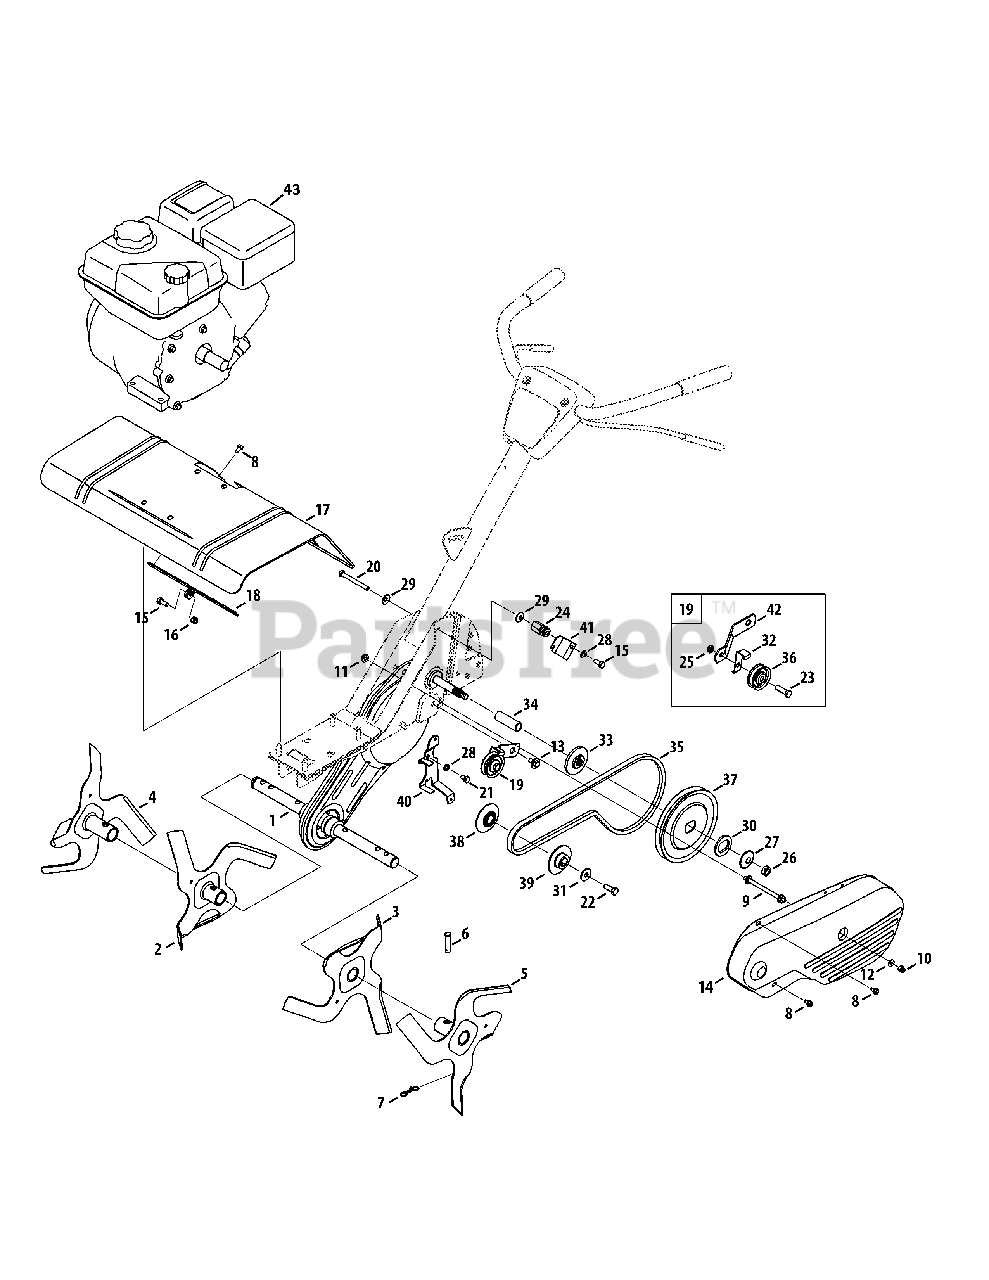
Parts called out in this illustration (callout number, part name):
1	Chain Case Assembly
2	Inner Tine Assembly, RH
3	Inner Tine Assembly, LH
4	Outer Tine Assembly, RH
5	Outer Tine Assembly, LH
6	Clevis Pin, .375 x 1.75
7	Bow Tie Cotter Pin
8	Screw, 1/4-20 x 0.500
9	Bolt, Belt Cover
10	Nut, 1/4-28, Lock
11	Nut, 5/16-18, Flange Lock
12	Flat Washer, .271 x .630 x .065
13	Shoulder Screw, .560 x .165 5/16-18
14	Belt Cover
15	Hex Head Screw, 5/16-18 x .75
16	Nut, 5/16-18, Flange Lock
17	Tine Shield
18	Bracket, Tine Shield
19	Idler Bracket Assembly
20	Hex Head Screw, 5/16-18 x 3.00
21	Hex Head Screw, 5/16-24 x .625
22	Hex Head Screw, 3/8-24 x 1.00
23	Hex Head Screw, 3/8-16 x 1.25
24	Hex Nut, 5/16-18
25	Jamlock Nut, 3/8-16
26	Nut, 1/2-20, Jam
27	Washer, .531 x 1.62 x .045
28	Lock Washer, 5/16
29	Bell Washer, .340 x .872 x .060
30	Flat Washer, 1.26 x 1.87 x .150
31	Bell Washer, .396 x 1.140 x .095
32	Belt Keeper
33	Pulley Adaptor
34	Spacer, .64 ID x 2.4
35	Belt, 4L x 41.9 LG
36	Pulley 1.88 OD
37	Pulley 6.00 OD
38	Inner Engine Pulley
39	Outer Engine Pulley
40	Belt Keeper Bracket
41	Cable Guide Bracket
42	Idler Bracket
43	Replacement Engine
